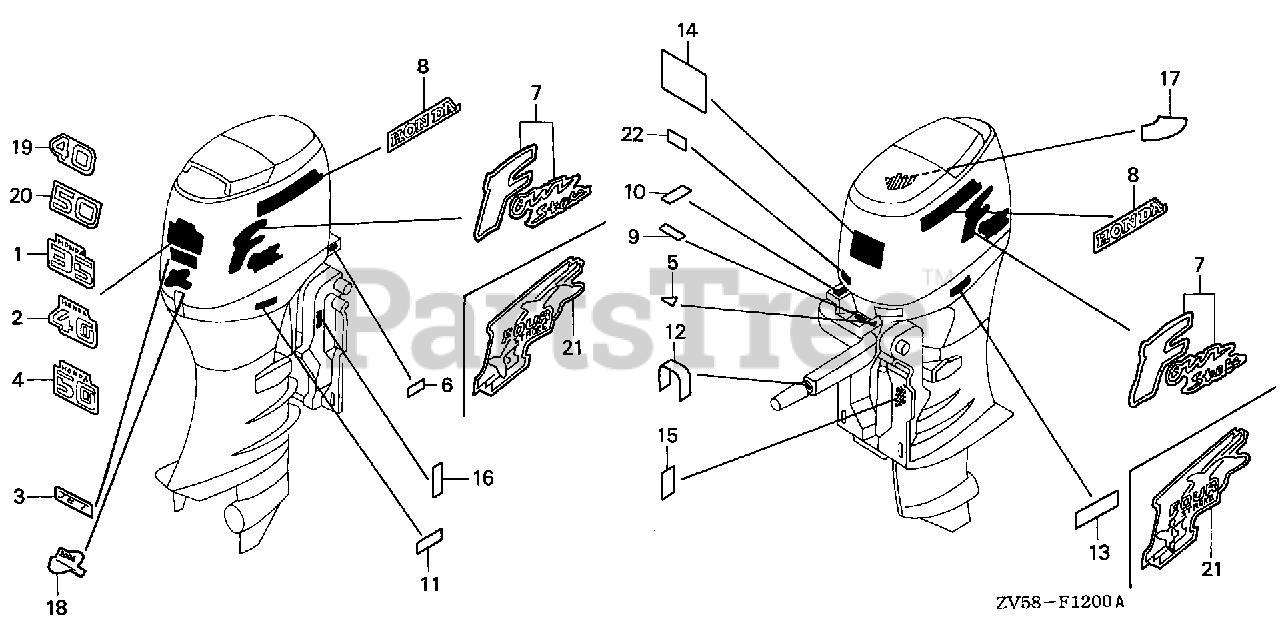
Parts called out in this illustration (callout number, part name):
2	MARK, RR. (40)
7	MARK, SIDE EMBLEM
8	MARK, SIDE STRIPE
9	LABEL, SPECIFICATION (NMMA)
11	LABEL, OIL CAUTION (ENGLISH)
13	LABEL, STORING CAUTION (ENGLISH)
14	LABEL, CAUTION OPERATOR (ENGLISH)
15	LABEL, ASSIST TILT CAUTION (ENGLISH)
16	MARK, ASSIST LEVER (ENGLISH)
17	MARK, EMERGENCY START (ENGLISH)
18	MARK, ENVIRONMENT (EPA 2006)
